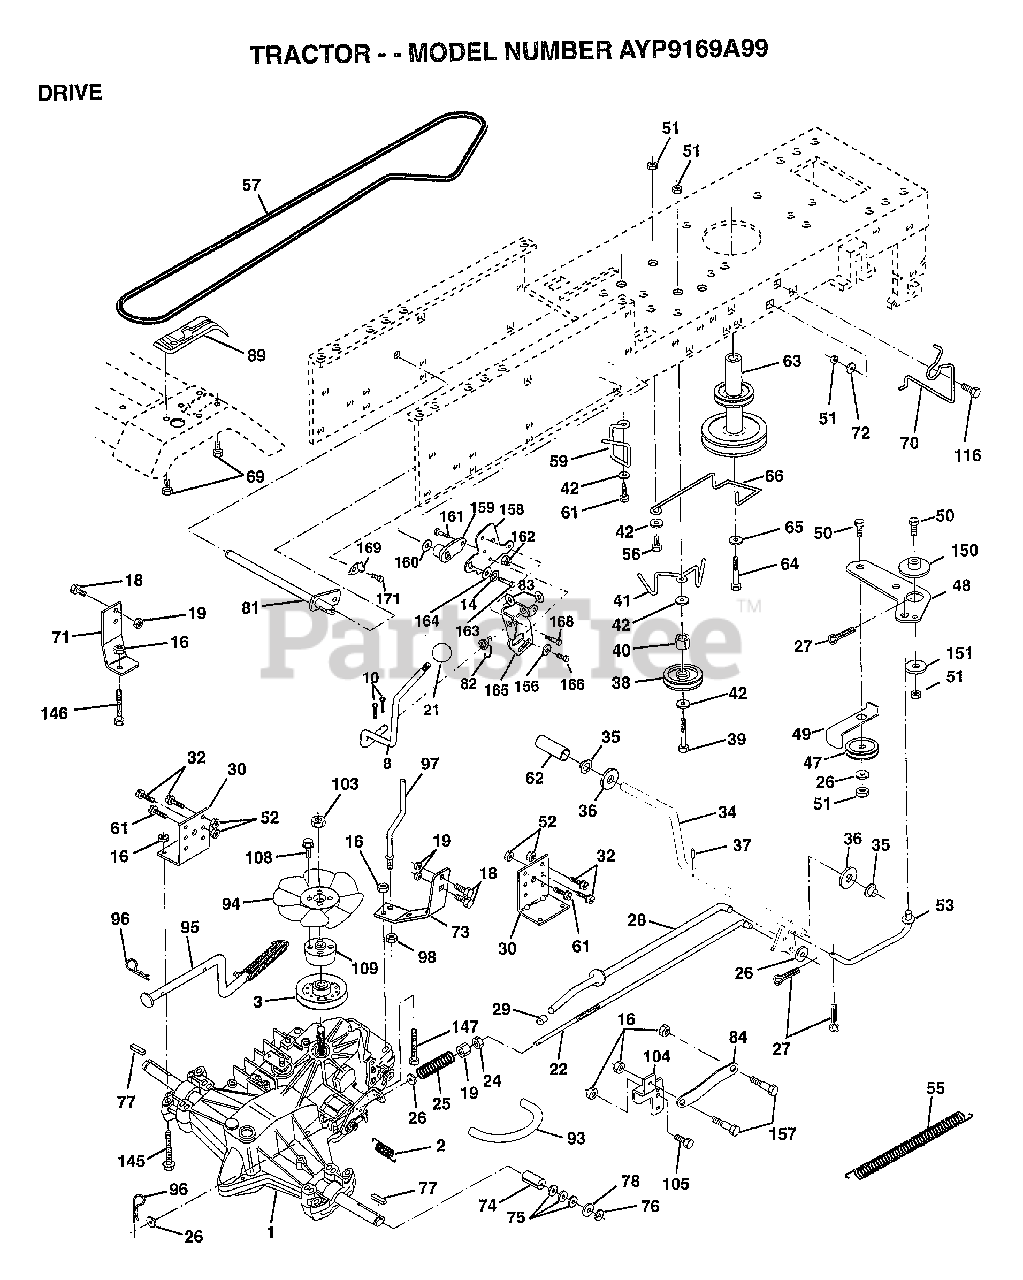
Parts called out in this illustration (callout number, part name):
1	TRANSAXLE HYD 0319-0500
2	SPRING RET BRAKE
3	PULLEY.4.20.HYDRO
8	ROD.SHIFT.FENDER.ADJ.LT.CRD
10	PIN COTTER 1/8
14	LOCKWASHER
16	NUT
18	BOLT
19	NUT
21	KNOB T (1/2-HOLE)
22	ROD.BRAKE.HYDRO.
24	NUT
25	SPRING ROD LT
26	WASHER
27	COTTER PIN
28	ROD.BRAKE.PARK.LT
29	PLUNGER CAP T
30	TRANSAXLE MTG BKT
32	BOLT
34	SHAFT ASM-PEDAL F
35	NYLON BEARING
36	WASHER LT
38	FLAT IDLER PULLEY
39	BOLT
40	SPACER T
41	"KEEPER,BELT.IDLER FLAT"
42	WASHER
48	BELLCRANK.CLUTCH
49	RETAIN BELT
53	"LINK, CLUTCH T"
55	"SPRING, RETURN LT"
57	BELT-V.HYDR.84.61
59	KEEPER BELT CNTSP
61	SCREW
62	PEDAL COVER T
63	PULLEY.ENGINE
64	BOLT
65	LOCKWASHER
66	KEEPER-BELT
69	SCREW HEXWSH H-L
70	KEEPER BELT ENG
71	STRAP.TORQ.LH.HYD
72	WASHER
73	STRAP.TORQ.RH.HYD
74	SPACER SPLIT
75	WASHER
76	E-RING LT
77	SQUARE KEY
78	WASHER
81	SHAFT ASM.CROSS
82	"SPRING,TORSION"
83	WASHER
84	LINK.TRANSAXLE.HYDR
89	CONSOLE.SHIFT.LT
92	HEX BOLT
93	"LINE FUEL HYD 4"""
94	"FAN 7"" HYDRO"
96	RETAINER M
97	KEEPER.BELT.RH.HY
98	NUT
104	ARM.CONTROL.PUMP
105	SCREW CAP 5/16-18
108	SCREW.HXHD.10-20
109	ADAPTOR.FAN.HYDRO
116	BOLT RDHD 3/8-16
145	BOLT.HEX.FLGHD
146	BOLT.HEX.FLGHD.
147	BOLT.HEX.FLGHD
150	BUSHING.BELLCRANK.GRD.DR
151	WASHER
156	WASHER.SRRTD.5/16
157	"BOLT,SHOULDER"
158	BRKT.SHIFT.MOUNT
159	HUB.SHIFT
160	WASHER
161	BOLT T
164	WASHER.5/8X.281X10GA
165	BRKT.PIVOT.LEVER
166	BACKPLATE
168	BOLT.SHOULDER.5/16-18X.561
169	PLATE.FASTENING
171	SCREW LT
